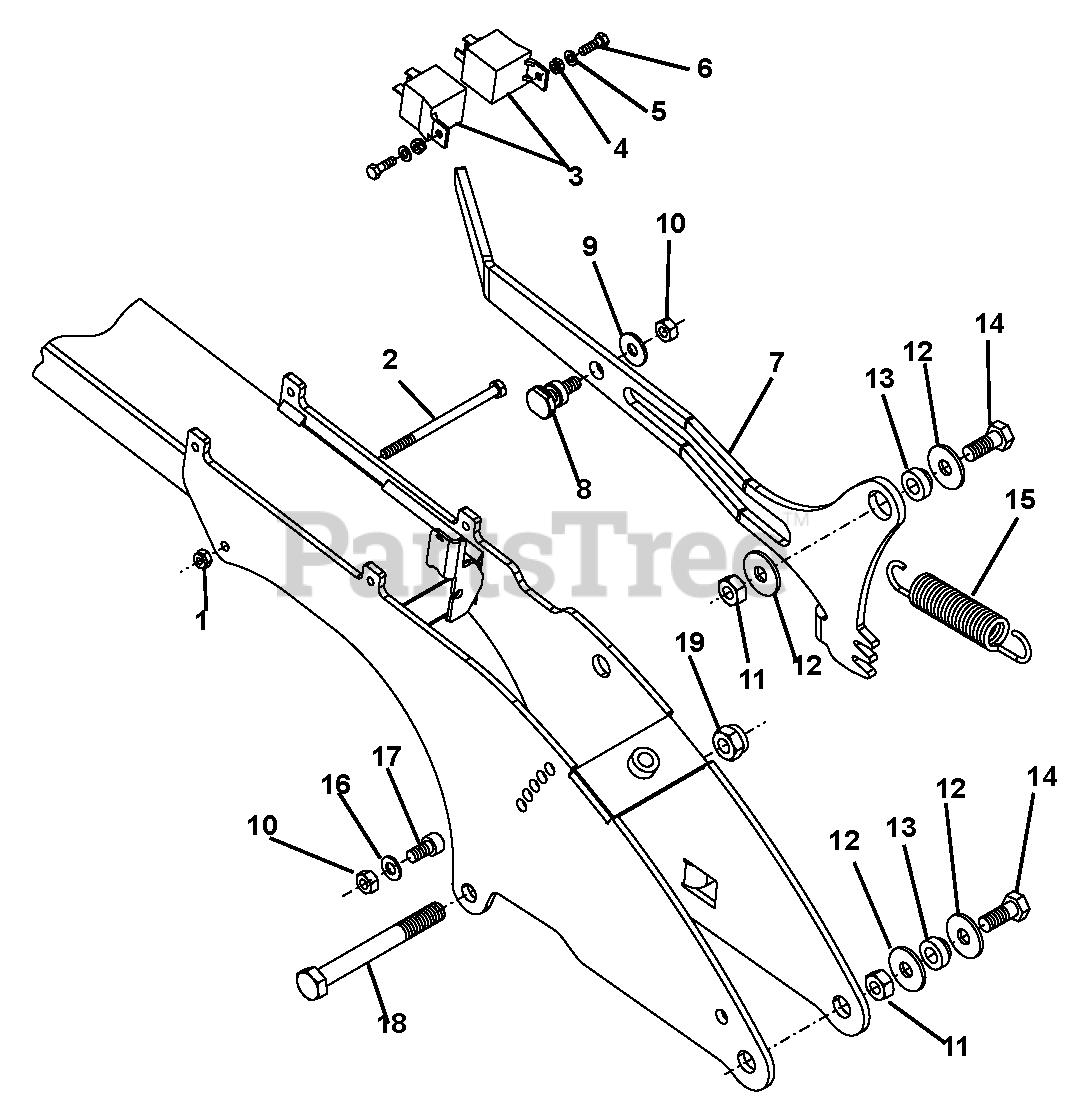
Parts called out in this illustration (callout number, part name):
1	Nut, Lock D985 M6
2	Bolt, Hex D931 M6 x 100
4	Nut, Lock M5
5	Washer, D125 5.3 x 10 x 1
6	Bolt, Hex D933 M5 x 16
9	Washer, M8
10	Nut, Hex D934 M8
11	Nut, Lock D934 M10
12	Washer, D9021 10,5 x 30 x 2,5
13	Bearing Bushing
14	Bolt, Hex D933 M10 x 25
15	Spring, Tension, 3.2/19.3 x 122
16	Washer, M8
17	Screw, D912 M8 x 16
18	Bolt, Hex D931 M12 x 110
19	Nut, Lock M12
